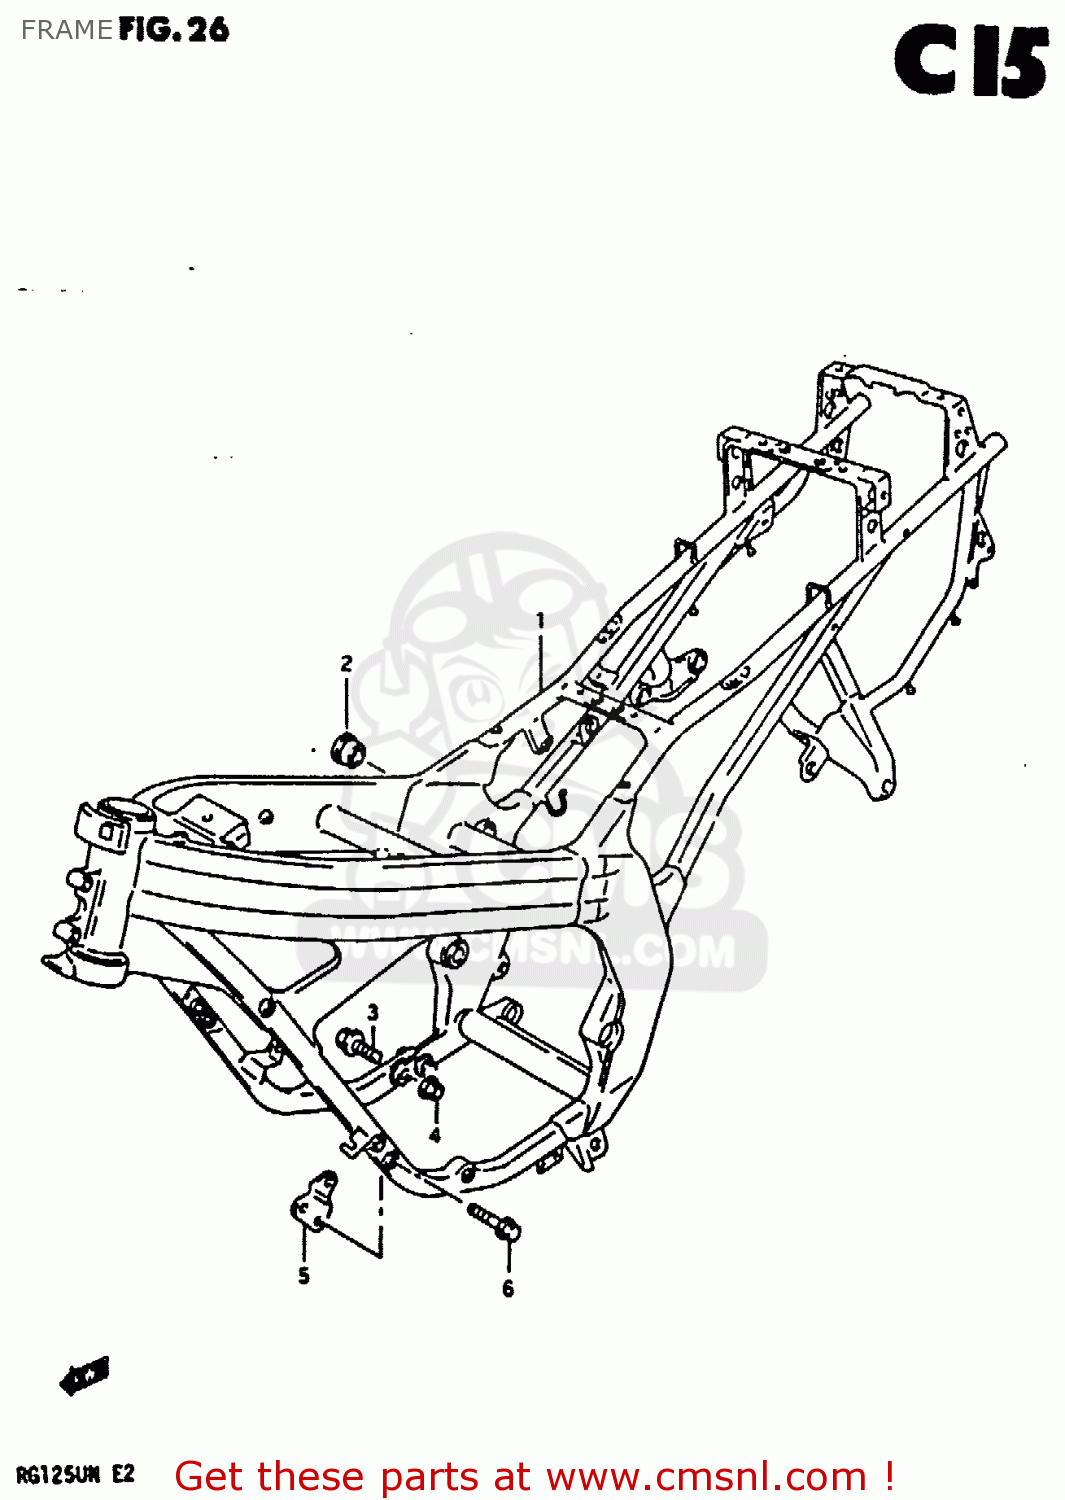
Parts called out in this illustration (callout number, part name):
1	FRAME (SILVER)
2	PLUG
3	BOLT, FRAME JOINT
4	NUT
5	PLATE,ENG MTG(SILVER)
6	BOLT
